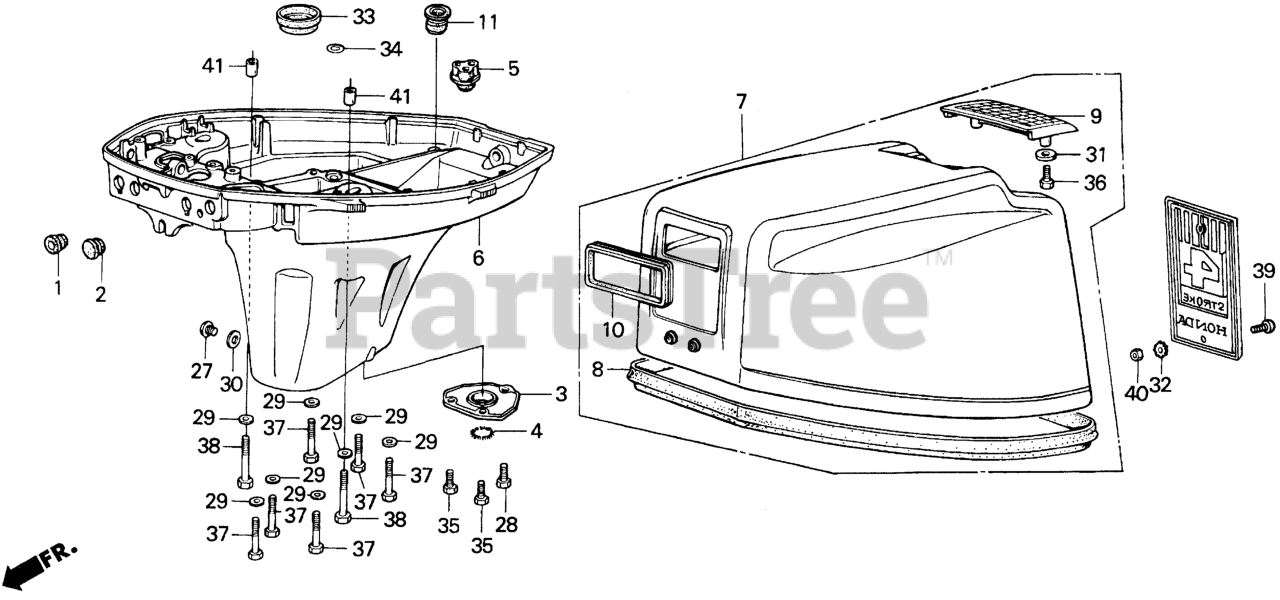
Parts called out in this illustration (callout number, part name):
1	GROMMET A, WIRE
2	GROMMET C, OIL CASE
3	PLATE, EX.
4	BAND, EX. SEAL
5	MANIFOLD, TUBE
6	CASE, OIL *B107* (SENIOR BLUE)
7	COVER, ENGINE *NH24* (CERAMIC WHITE)
8	SEAL, ENGINE COVER (NOT AVAILABLE)
9	HANDLE, TILT *NH105* (MAT BLACK)
10	SEAL, RECOIL
11	GROMMET, WATER CHECK
27	BOLT, OIL CHECK
28	BOLT, HEX. (6X12)
29	WASHER, PLAIN (6MM) Use from Frame SN 4800713.
30	WASHER, NYLON (8MM)
31	WASHER (6MM)
32	WASHER, LOCK (4MM) (NOT AVAILABLE)
33	SEAL, COUPLING (25X40X22)
34	O-RING (9.8X1.9)
35	BOLT, HEX. (6X12)
36	BOLT, HEX. (6X16)
37	BOLT, HEX. (6X32) (NOT AVAILABLE)
38	BOLT, HEX. (6X40)
39	SCREW, PAN (4X10)
40	NUT, HEX. (4MM)
41	PIN A, DOWEL (8X14)
